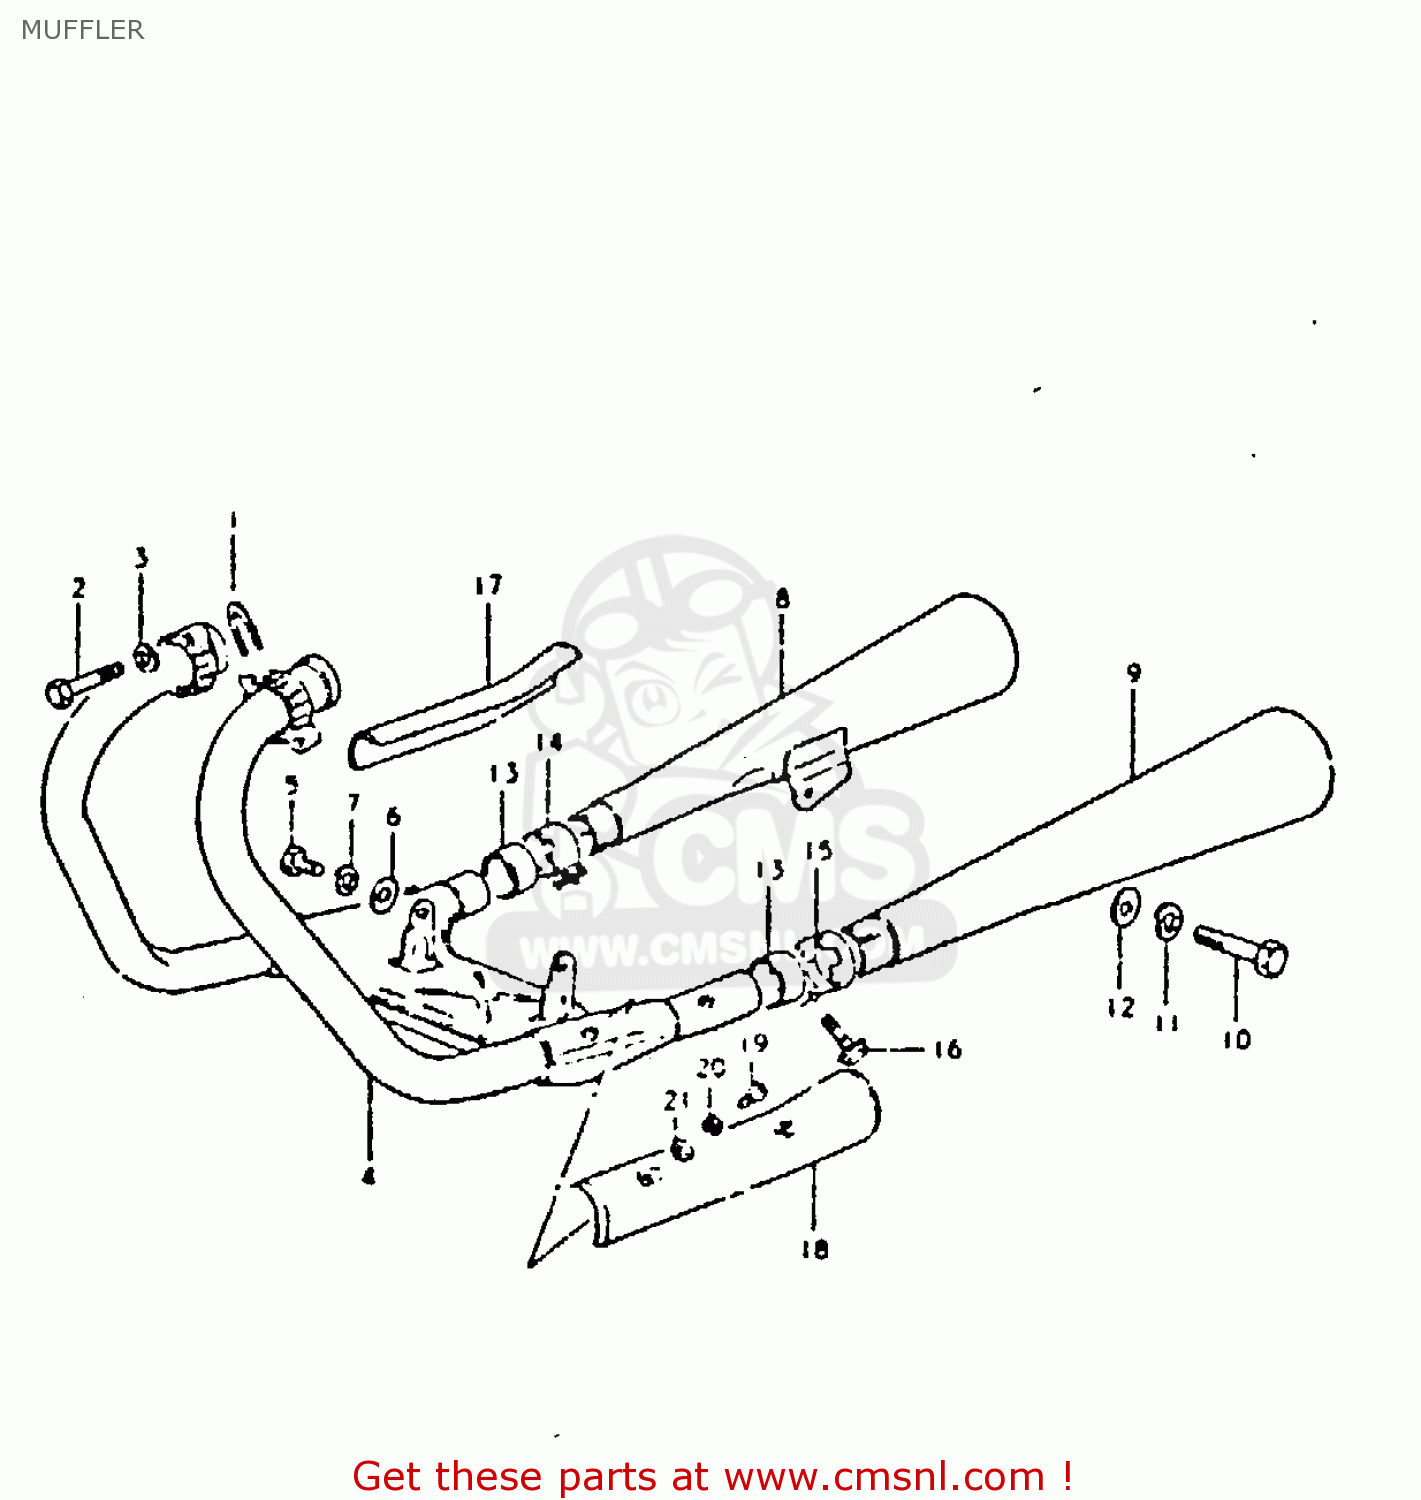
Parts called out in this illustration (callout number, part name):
1	GASKET,EXHAUST PIPE (NAS)
2	BOLT
3	LOCK WASHER
4	PIPE,EXHAUST
5	BOLT
6	LOCK WASHER
7	WASHER
8	BODY,MUFFLER
9	BODY,MUFFLER
10	BOLT 10X30
11	LOCK WASHER
12	WASHER
13	CONNECTOR,MUFFLER
14	CLAMP,MUFFLER CONNECTOR,R
15	CLAMP,MUFFLER CONNECTOR,R
16	BOLT
17	COVER,MUFFLER
18	COVER,MUFFLER,LEFT
19	SCREW
20	LOCK WASHER
21	WASHER
